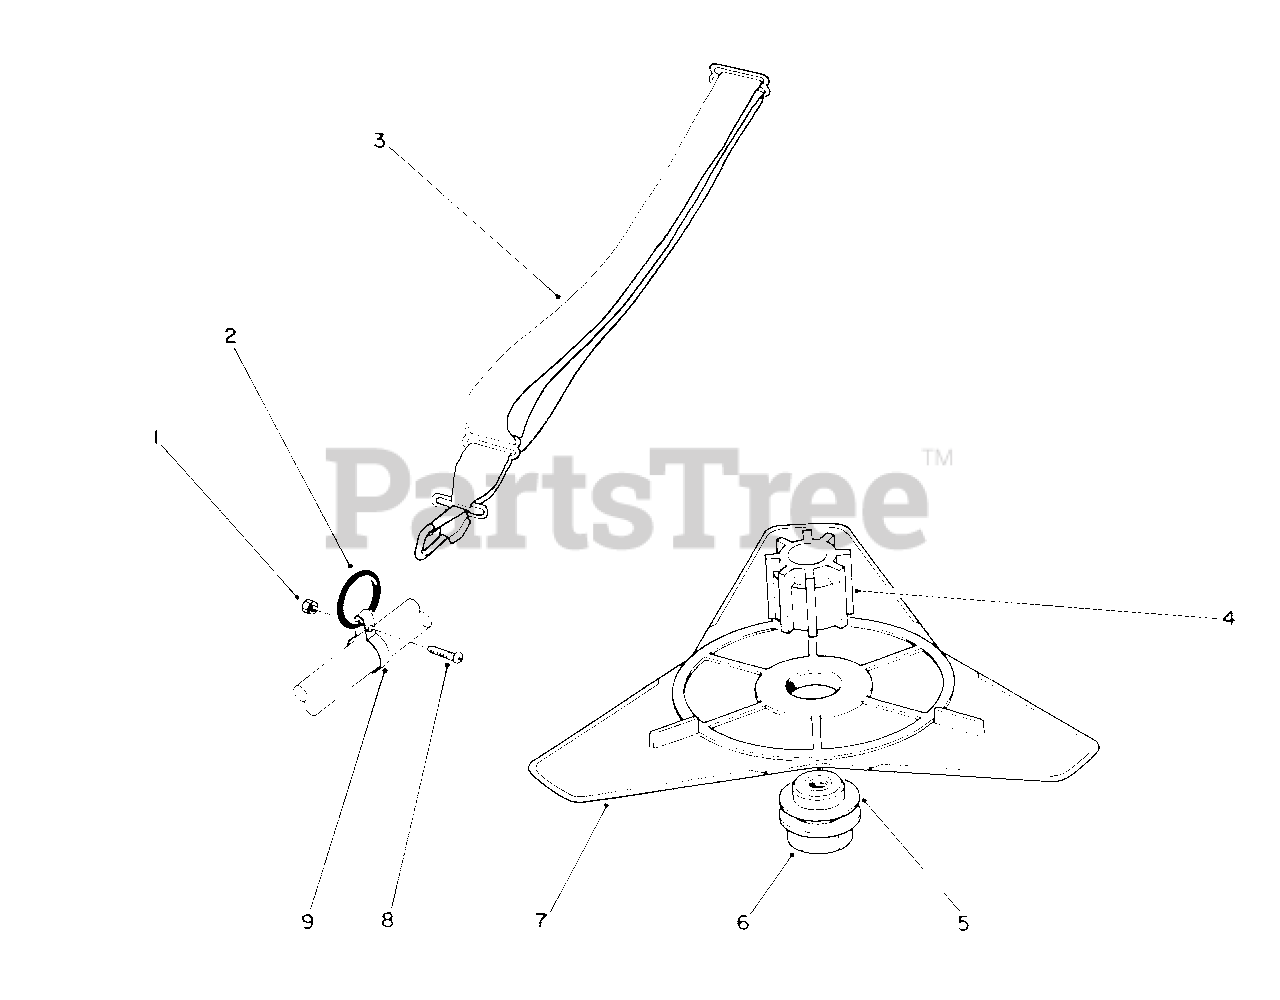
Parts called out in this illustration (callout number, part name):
3	Shoulder Harness
4	Adapter-Blade
6	Nut-Adapter
7	Blade-Flex 10"
9	Clamp
